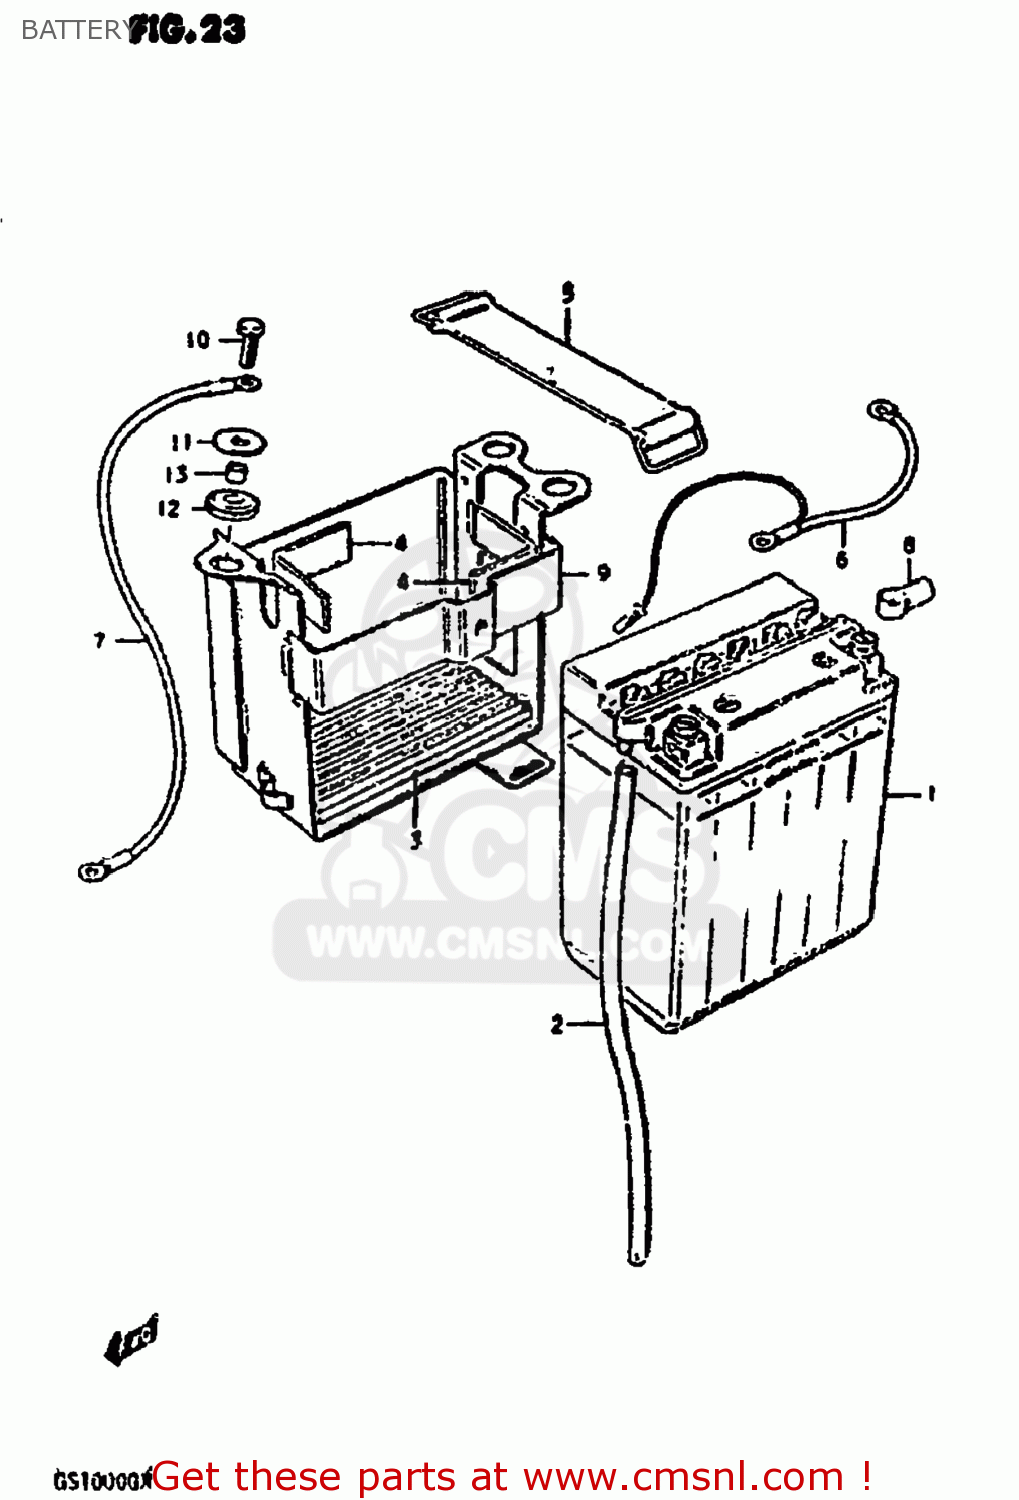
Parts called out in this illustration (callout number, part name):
1	BATTERY ASSY (12V)
2	HOSE,BATTERY EXHAUST
3	PROTECTOR,BATTERY
4	PROTECTOR(20X90)X4
5	BAND
6	WIRE,BATTERY PLUS
7	LEAD WIRE,BATTERY(-)
8	CAP,TERMINAL
9	HOLDER,BATTERY
10	BOLT, UPPER
11	WASHER(6,5X22X1.6)
12	CUSHION
13	SPACER(6.2X8.3X5.7)
